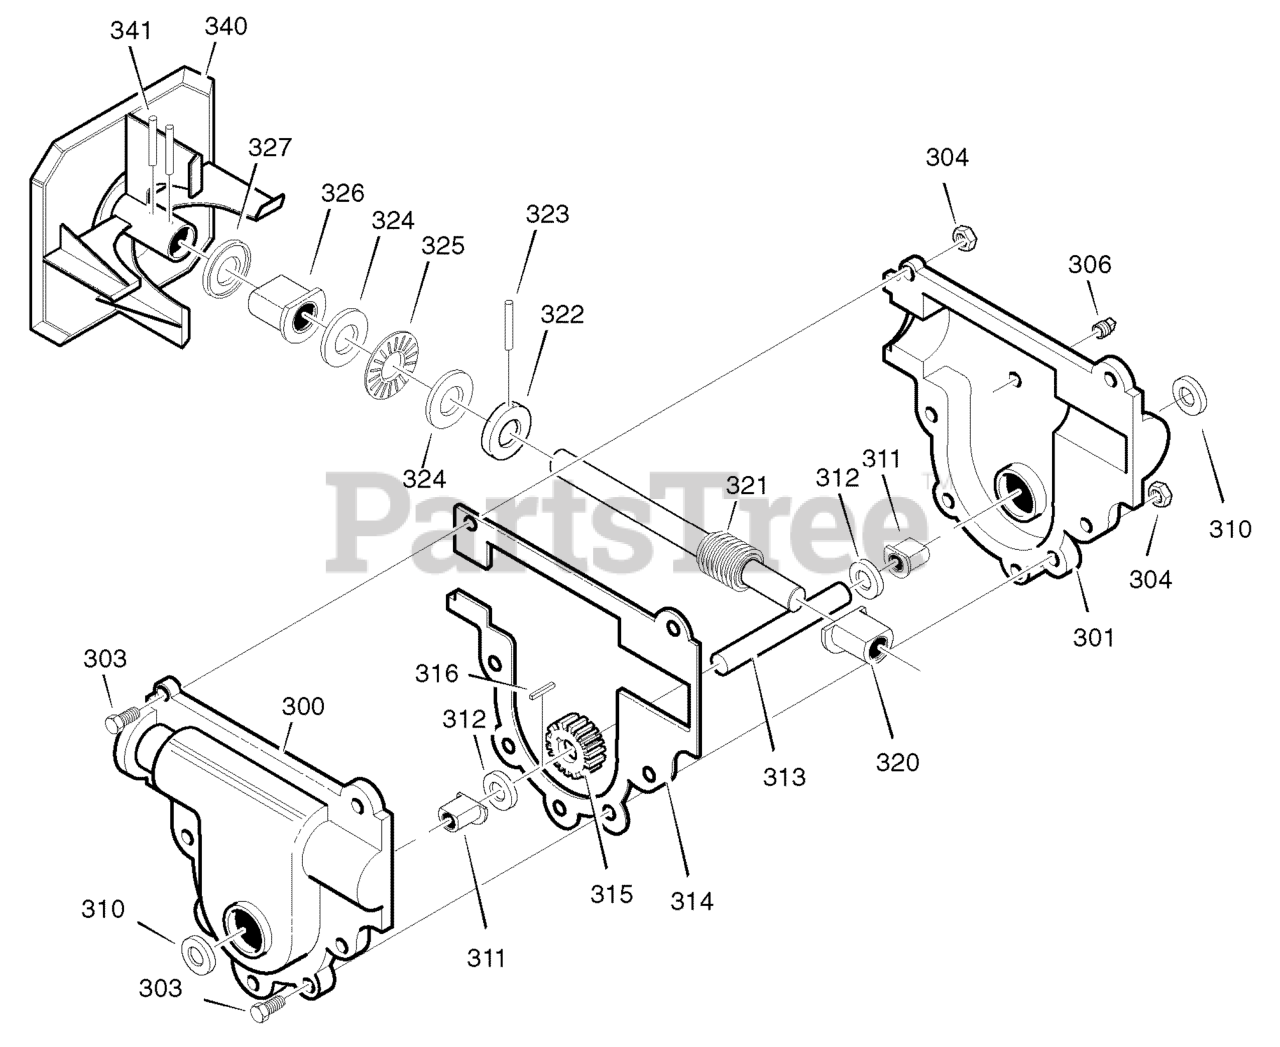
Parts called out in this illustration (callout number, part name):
300	CASE, GEAR, RH
301	CASE, GEAR, LH
303	SCREW,1/4-20X.75
304	NUT,1/4-20
306	SCREW, 3/8-16 x 0.50
310	SEAL, OIL
311	BEARING, FL
312	WASHER, FLAT
313	SHAFT, AUGER OUTPUT
314	GASKET, GEAR BOX
315	GEAR, WORM
316	KEY, WOODRUFF #61
320	BRNG, FL
321	SHAFT, AUGER INPUT (IMPELLER)
322	COLLAR, THRUST
323	PIN, SPRING
324	WASHER, FLAT
325	BRNG, ROLL
326	BRNG, FL
327	SEAL, OIL
341	PIN, SPRING
